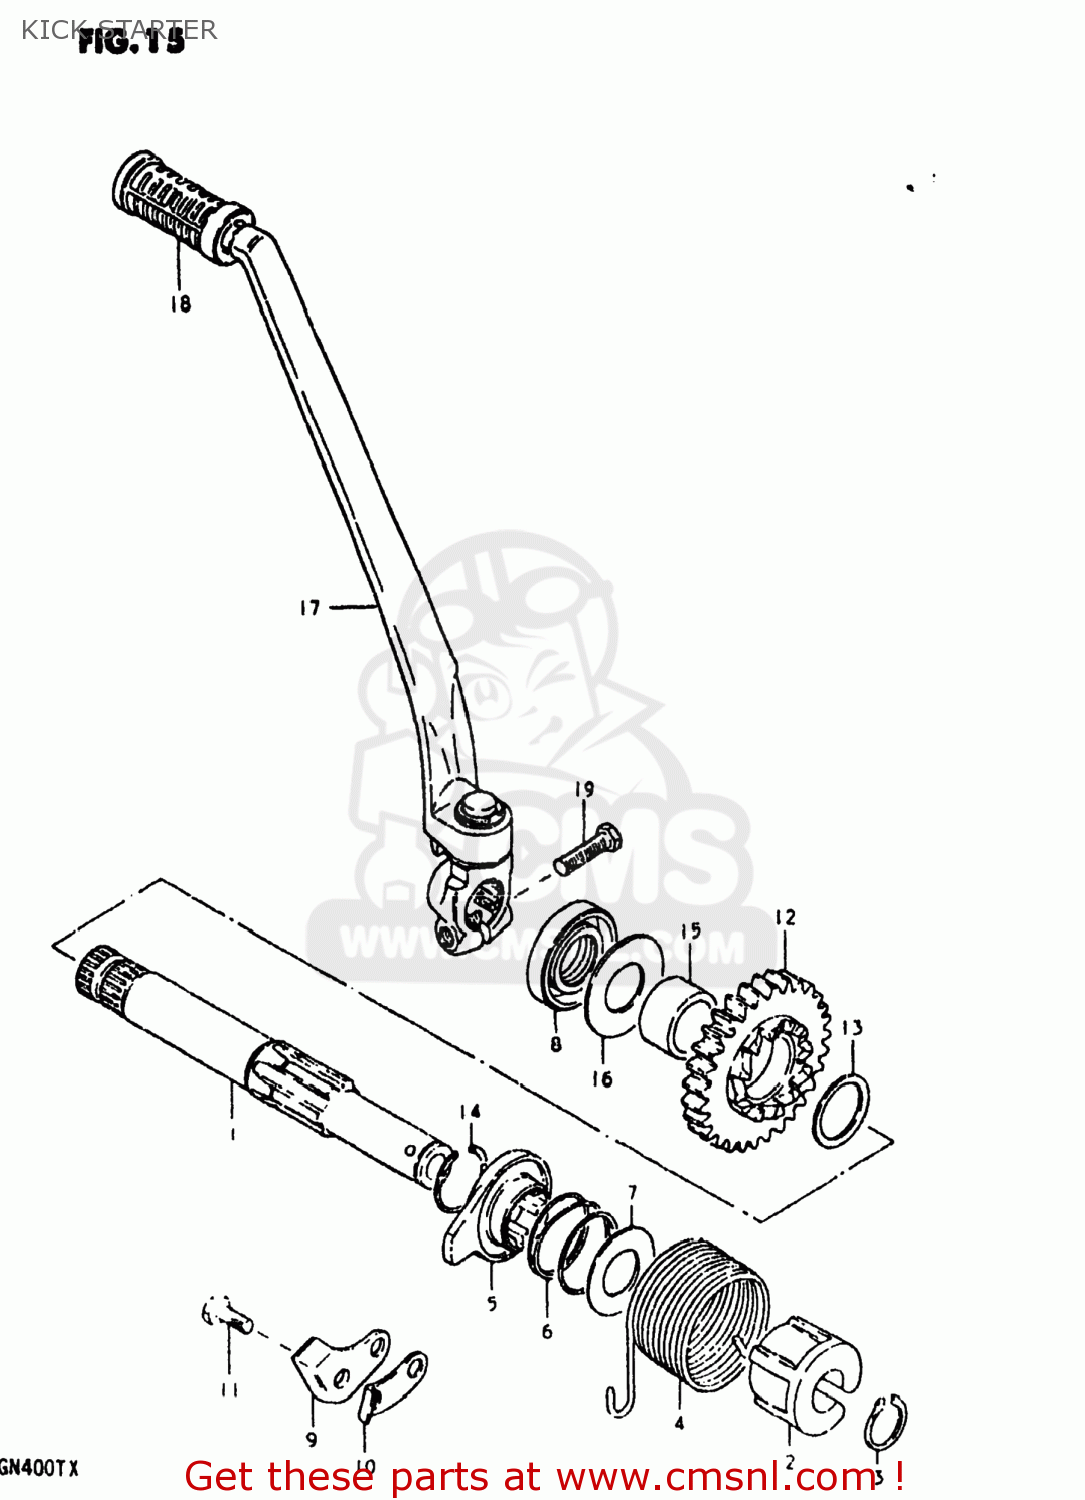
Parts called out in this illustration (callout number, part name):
1	SHAFT,KICK STARTER
2	GUIDE,KICK STARTER SFT SPRING
3	CIRCLIP
4	SPRING
5	STARTER,KICK
6	SPRING
7	PLATE
8	SEAL,OIL(20X37X7)
9	GUIDE,KICK STARTER
10	STOPPER,KICK STARTER
11	BOLT
12	GEAR,KICK STARTER DRIVE(NT:29)
13	WASHER,LOCK
14	CIRCLIP
15	SPACER (20X28X13.8)
16	PLATE, OIL RESERVOR
17	LEVER ASSEMBLY,KICK STARTER
18	RUBBER,KICK STARTER PEDAL
19	BOLT
